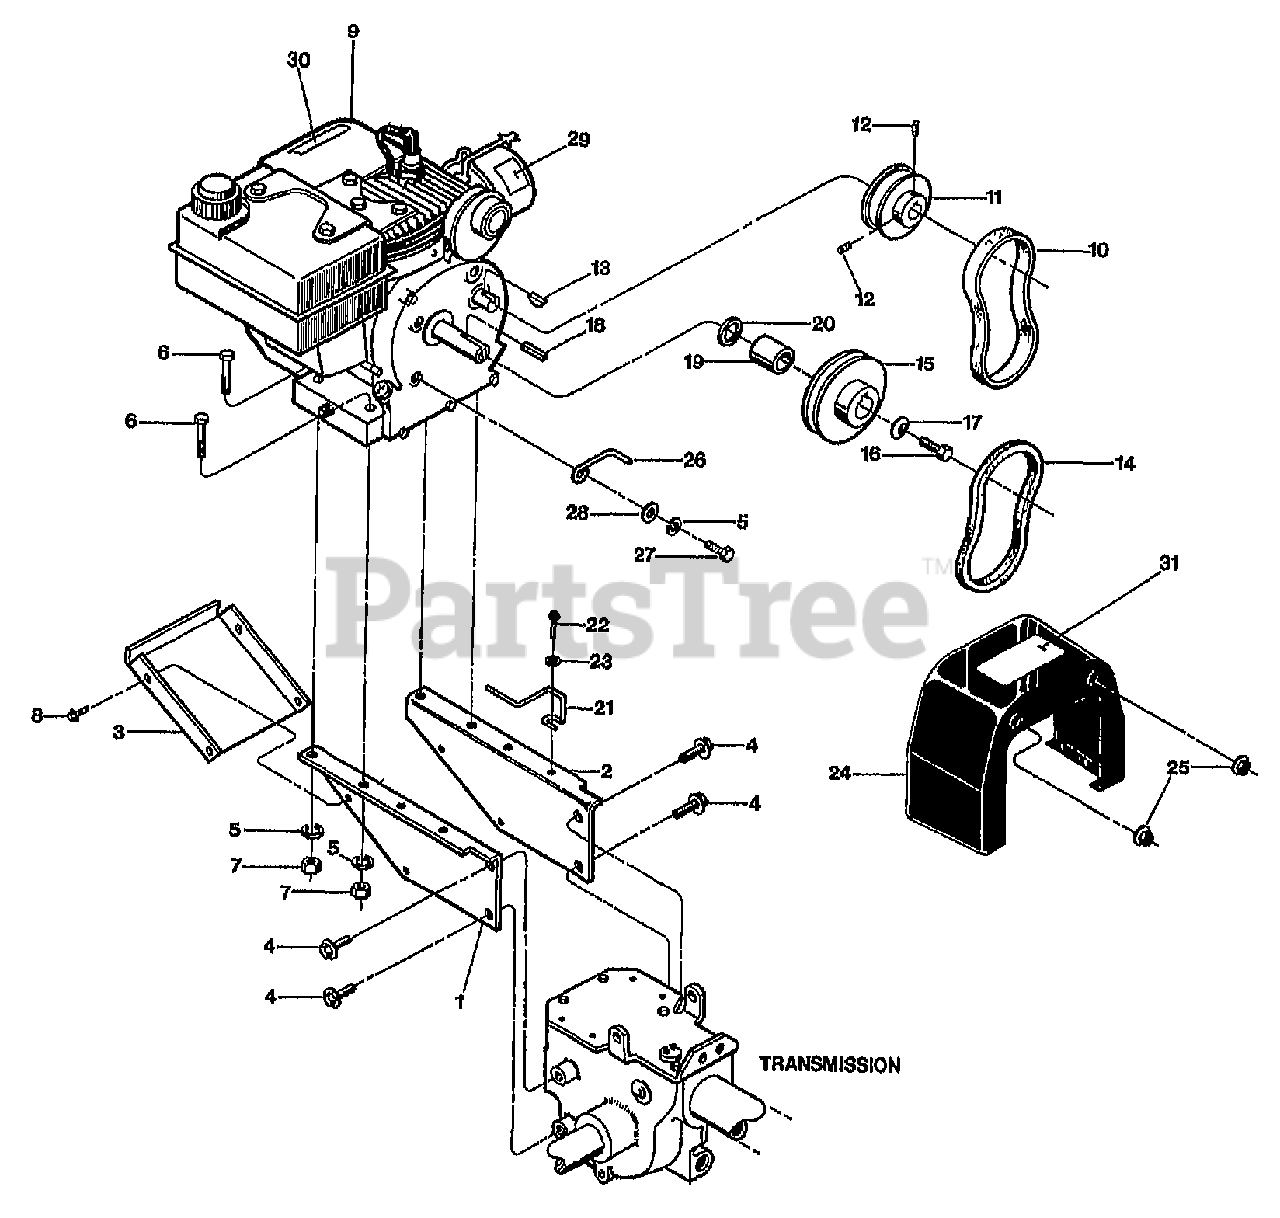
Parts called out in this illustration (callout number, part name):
1	BRKT-ENG LT P4
2	BRKT-ENG RT PNT
3	PAN-ENG BRKT PNT
4	SCR-HFLK 5/16-18X.75 ZP
5	WASHER-LK .312 ZP
6	SCR-HH 5/16-18X1.5 G5 ZP
7	NUT-HEX 5/16-18 ZP
8	SCR-HW M10-32X.5 THRD ROLL
9	ENGINE, FOR TILLER MODELS 15006 AND 12079 ONLY
10	BELT-FLAT (SEE BELT SET BELOW)
11	PULLEY-REV DRILL/TAP
12	SCR-SS 1/4-20 X .25
13	KEY-WOODRUFF #5
14	BELT-V GROOVE FWD SMFRAME (SEE BELT SET BELOW)
15	PULLEY-ENGINE MACH
16	SCR-HH 3/8-24X1.0 G5 ZP
17	WASHER-.994X.413X.145
18	KEY-.188 SQX1.0
19	SPACER-.938X.755X1.44
20	SHIM-1.0X.7656X.031
21	GUIDE-BELT FWD
22	SCR-HWH 1/4-20 X .75 STH
23	WASHER-FLAT 1/4 SAE
24	COVER-BELT W/DECAL (INCL. 31)
24	COVER-BELT W/DECAL (INCL. 31) 150060400101 & UP
25	NUT-HFLK 5/16-18 ZP
26	STOP-BELT
27	SCR-HH 5/16-24X.75 G5 ZP
28	WASHER-FLAT 5/16 SAE
29	DECAL-HOT SURFACE
29	DECAL-HOT SURFACE 150060400101 & UP
30	DECAL-STARTING STABIL
31	DECAL-BELT COVER OPC
31	DECAL-BELT COVER 150060400101 & UP
